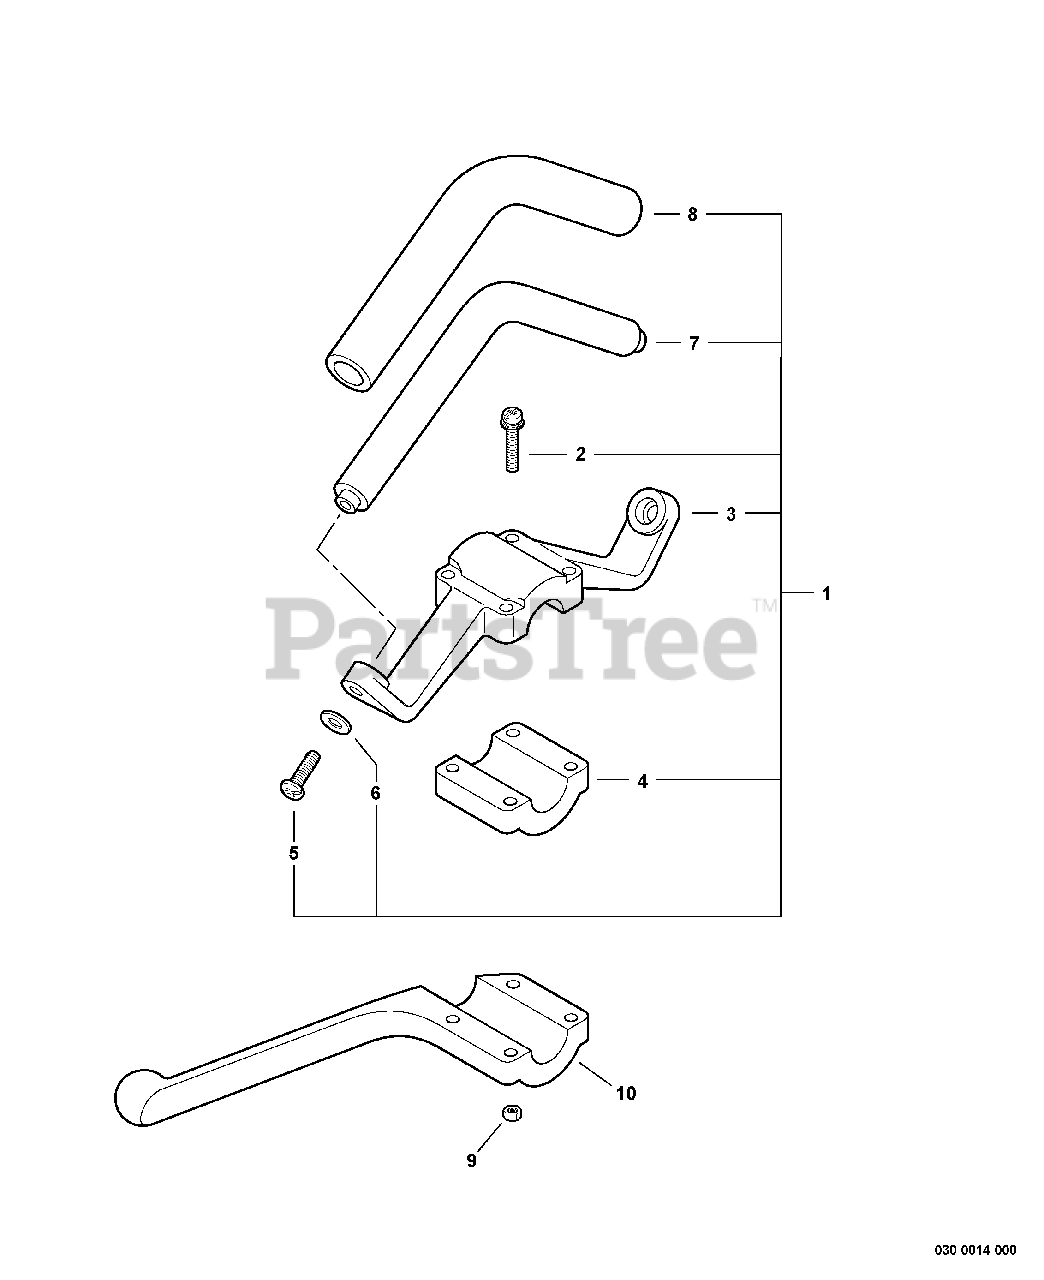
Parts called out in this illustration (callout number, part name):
1	HANDLE ASSY, SUPPORT
2	SCREW 5×35
3	BRACKET, HANDLE
4	BRACKET, HANDLE
5	SCREW, TAPPING 5×20
6	WASHER, FLAT 5.5×10×0.8
7	HANDLE, SUPPORT
8	GRIP, HANDLE
9	NUT M5
10	BAR, BARRIER
